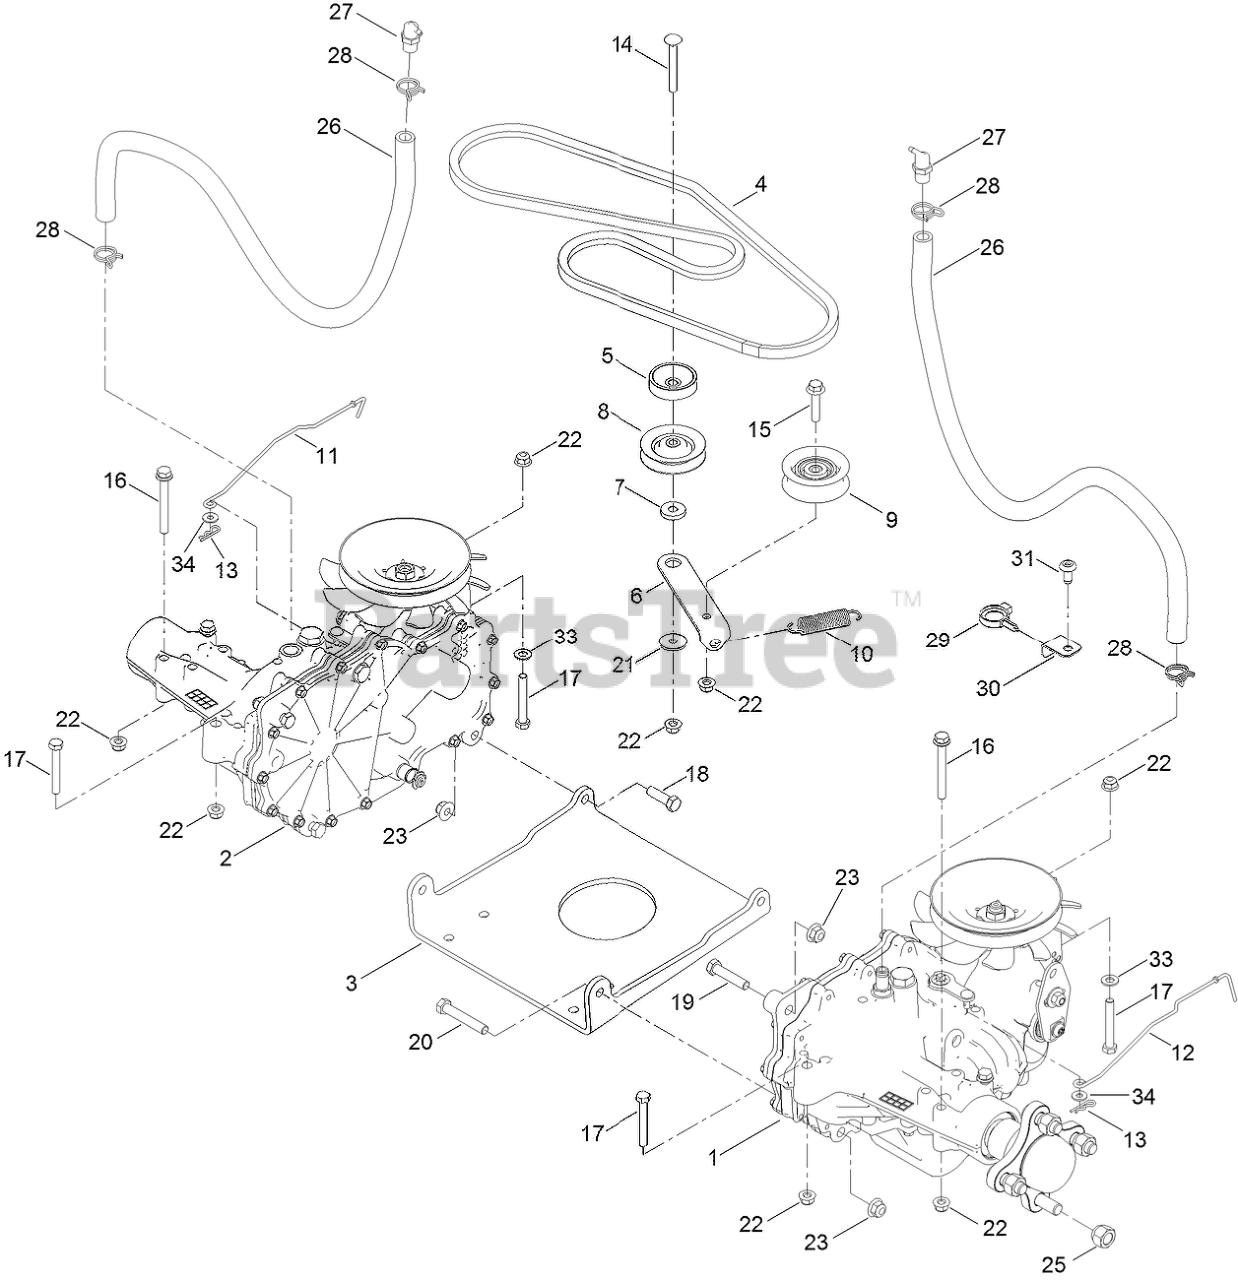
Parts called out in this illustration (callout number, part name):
1	LH HYDRO TRANSAXLE ASM
2	RH HYDRO TRANSAXLE ASM
3	PLATE- HYDRO
4	V-BELT
5	SPACER
6	ARM-IDLER
7	SPACER-IDLER ARM
9	PULLEY-IDLER, FLAT
10	SPRING-PEDAL, RETURN
11	ROD-BYPASS, RH
12	ROD-BYPASS, LH
14	SCREW-CARR
15	SCREW-HHF
16	SCREW-HHF
17	SCREW-HH
18	SCREW-HH
19	SCREW-HH
20	SCREW-HH
21	WASHER-PIVOT
22	NUT-HF, NI
23	NUT-HF, NI
25	NUT-LUG
26	HOSE-HYDRO
27	BREATHER KIT
28	CLAMP-HOSE
29	CLAMP-HOSE
30	MOUNT-BRACKET
33	WASHER-PLAIN
34	WASHER
